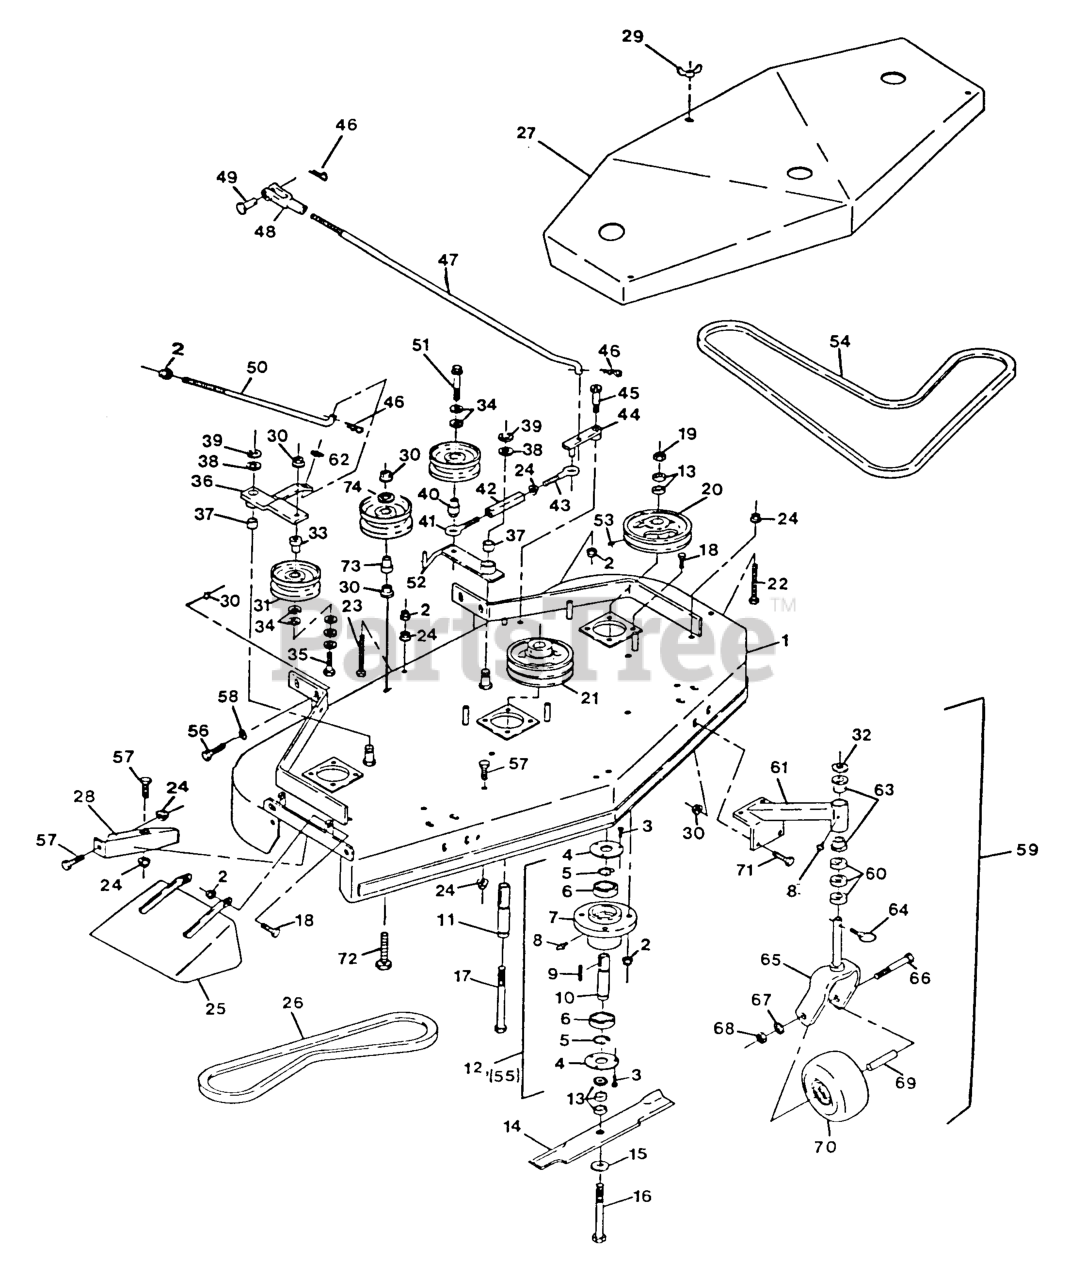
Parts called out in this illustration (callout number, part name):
3	SCRWMACH PHS
4	CAP,CUTTER HOUSING
5	RING,RETNG WLDS 5108-100
7	HOUSING,CUTTER
10	SPINDLE,CUTTER
12	HOUSING,CUTTER COMPLETE
17	SCREW-CAP, HH
20	PULLEY,CAST IRON
22	BOLT,TAP HH
23	BOLTTAP HH
26	BELT,FRONT DECK
28	BAFFLE-DOGLEG
32	WASHER-FLAT
33	BUSHING-IDLER
36	ARM,IDLER COMPLETE
37	BEARING,POWDERED METAL
38	WASHER-SPINDLE
40	BUSHING-ENGAGEMENT
41	EYEBOLT-THREAD, LH
42	BODY-TURNBUCKLE
43	EYEBOLT-THREAD, RH
45	BOLT,SHLDR KSKH
46	PIN-COTTER
48	YOKE-ADJUSTABLE
49	PIN-CLEVIS
50	ROD,BELT TENSION
53	SCREW-SET
54	BELT,BLADE DRIVE 48
55	HOUSING,CUTTER COMPLETE
60	SPACER-CASTER
63	BEARING-FLANGED
72	BOLT,TAP HH3/8-16X2-1/4
